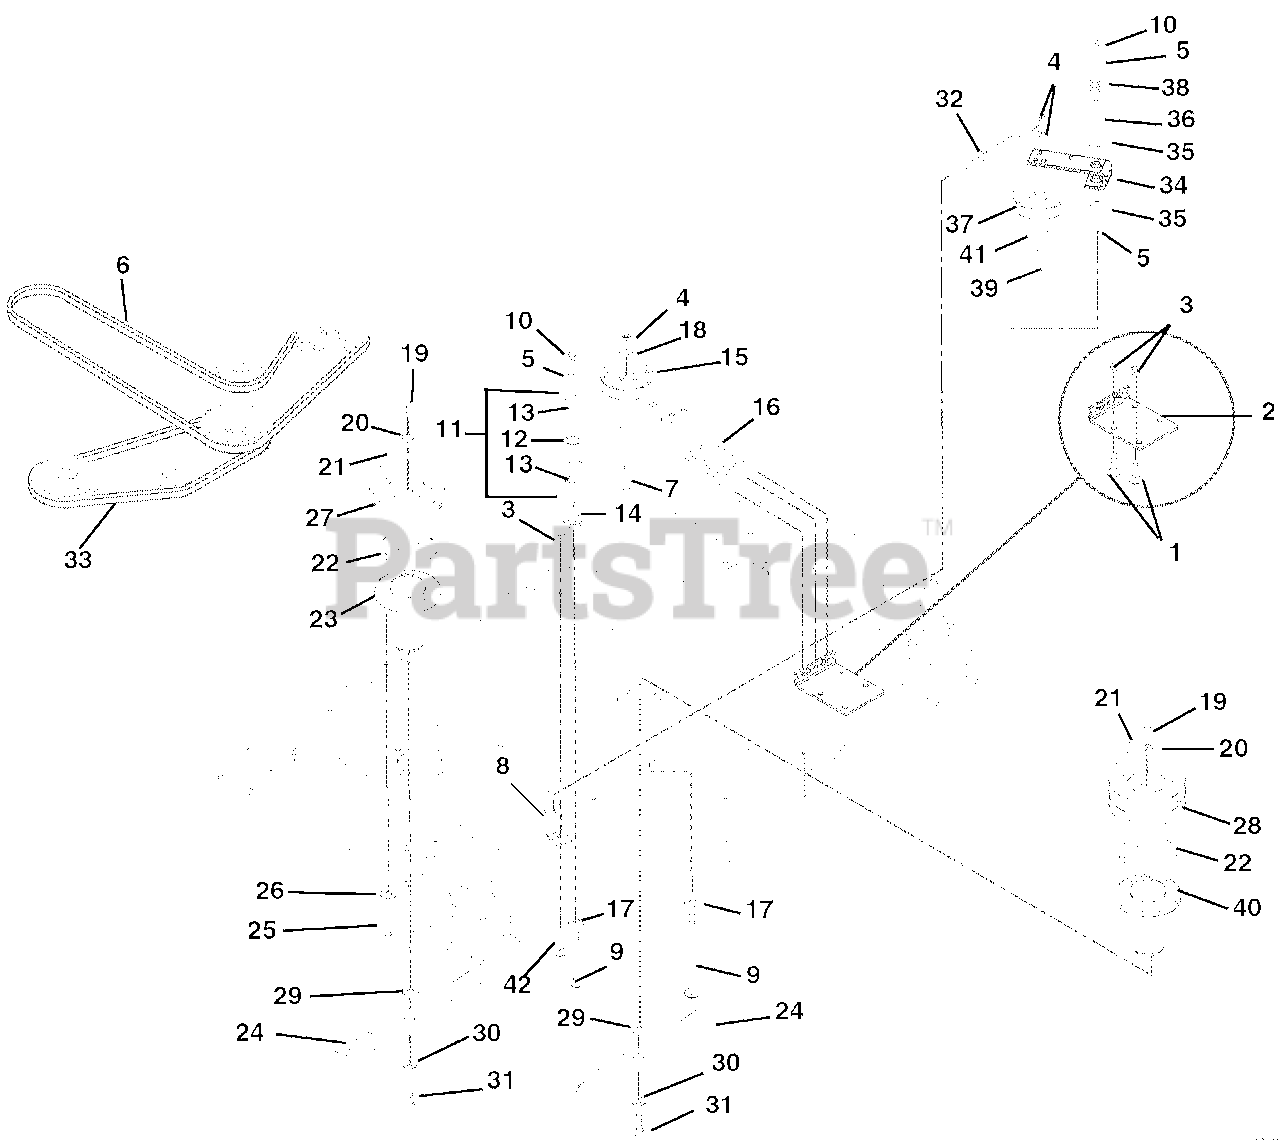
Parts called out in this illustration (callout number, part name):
1	Bolt, Round Head Square Neck .38-16 x .75 Grade 5
2	Bracket, Spring
3	Nut, Locking Top Flange .38-16
4	Nut, Locking Center .38-16
5	Washer, Flat Steel .531 x 1.25 x .10
6	V-Belt, B-Section 54.06 x .625
7	Bolt-Round Head Square Neck .38-16 x 2.75 Grade 5
8	Anchor, Spring
9	Bolt, Round Head Square Neck .50-13 x 3.50 Grade 5
10	Nut, Locking Top Flange .50-13
11	Assembly-Deck Idler Pivot Arm (Contains Items 12 & 13)
12	Weldment, Deck Idler Pivot Arm
13	Bearing, 1.00 x 1.12 x .75
14	Bearing, Pedestal Powdered Metal
15	Idler, Flat 4.00 x .38 (2.32W)
16	Spring, Extension
17	Washer, Flat Steel .755 x 1.375 x .062
18	Washer, Flat Steel .375 x 1.125 x .065
19	Bolt, Hex .38-16 x 1.00 Grade 8
20	Washer, Cupped Serrated .375
21	Key, Square .25 x .25 x 1.00
22	Slinger, Dust
23	Assembly, Maintenance Free Spindle
24	Blade 60" Mower CE
25	Bolt, Hex .38-16 x 1.00 Grade 5
26	Washer, Locking .38 x .094 Regular
27	Weldment, Spindle Sheave 6.00
28	Sheave, Double (6.25)
29	Washer, Flat .64 x 1.81 x .25
30	Washer, Bellville .63 x 1.625 x .14
31	Bolt, Hex .62-18 x 1.75 Grade 8
32	Spring, Extension (316, 317)
33	V-Belt B-Section 23.94 x .625
34	Arm, Idler Pivot
35	Bushing, Flange .762 x 1.00 x .58 x 1.48 Nylon
36	Spacer .56 x .75 x 2.44 Steel
37	V-Idler, 4.00 x .38
38	Spring, Compression .085 x .80 x 1.00
39	Bolt, Hex .38-16 x 2.25 Grade 5
40	Spindle Assembly (Center)
41	Washer, Flat Steel .406 x .812 x .05
42	Bolt, Round Head Square Neck .38-16 x 1.00 Grade 5
